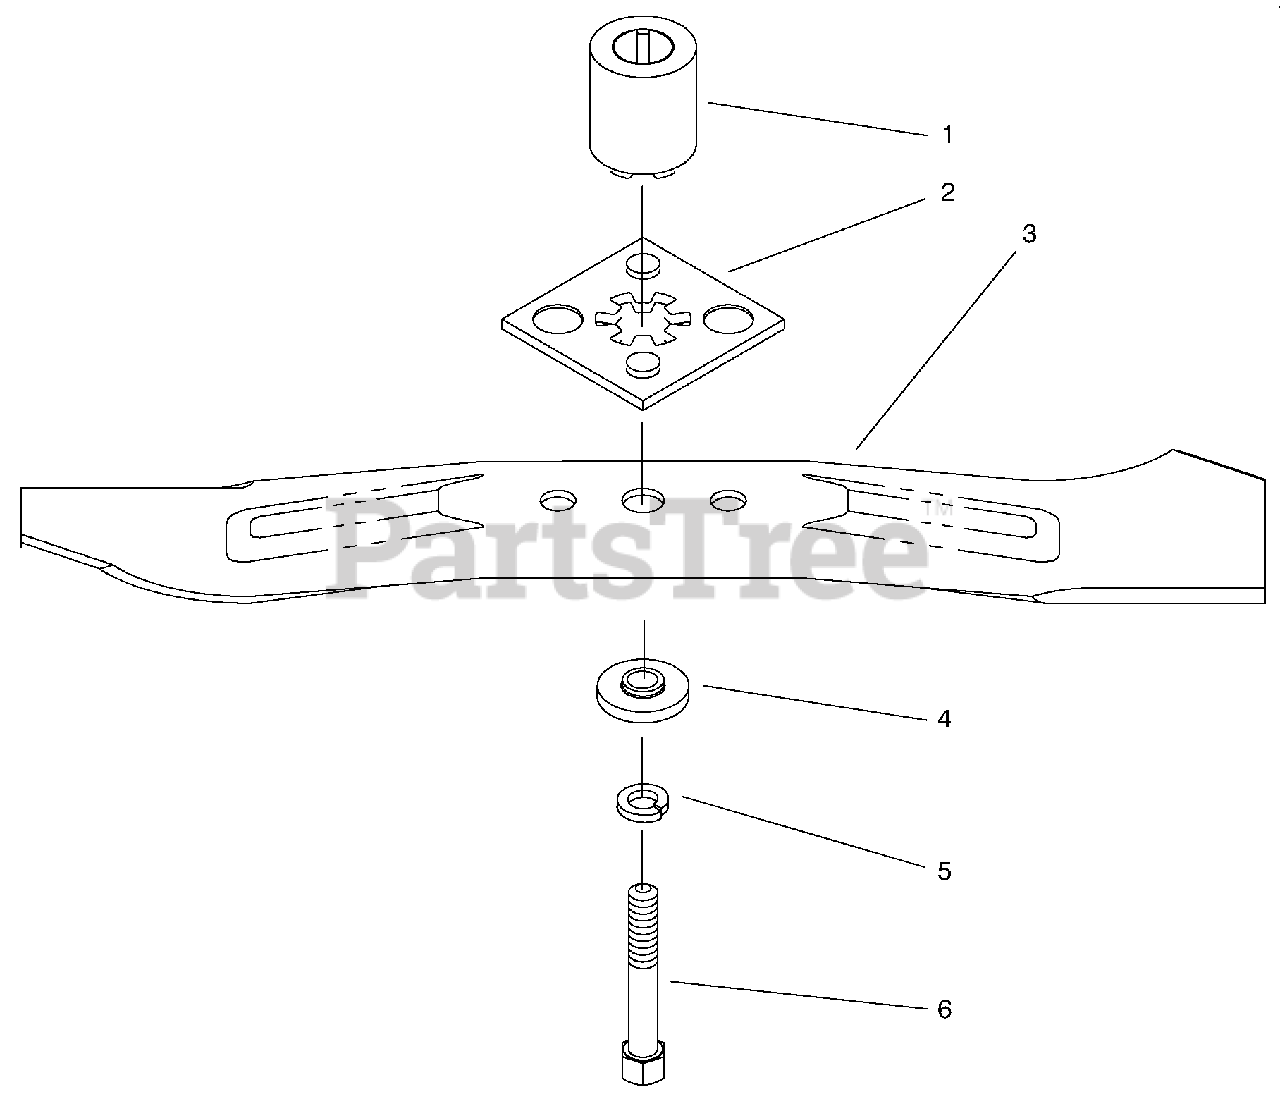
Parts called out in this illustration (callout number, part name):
1	Hub-Blade Driver
2	Plate-Blade Driver
3	Blade-48cm
4	Spacer-Blade
5	Washer-Lock
6	Bolt-Blade
